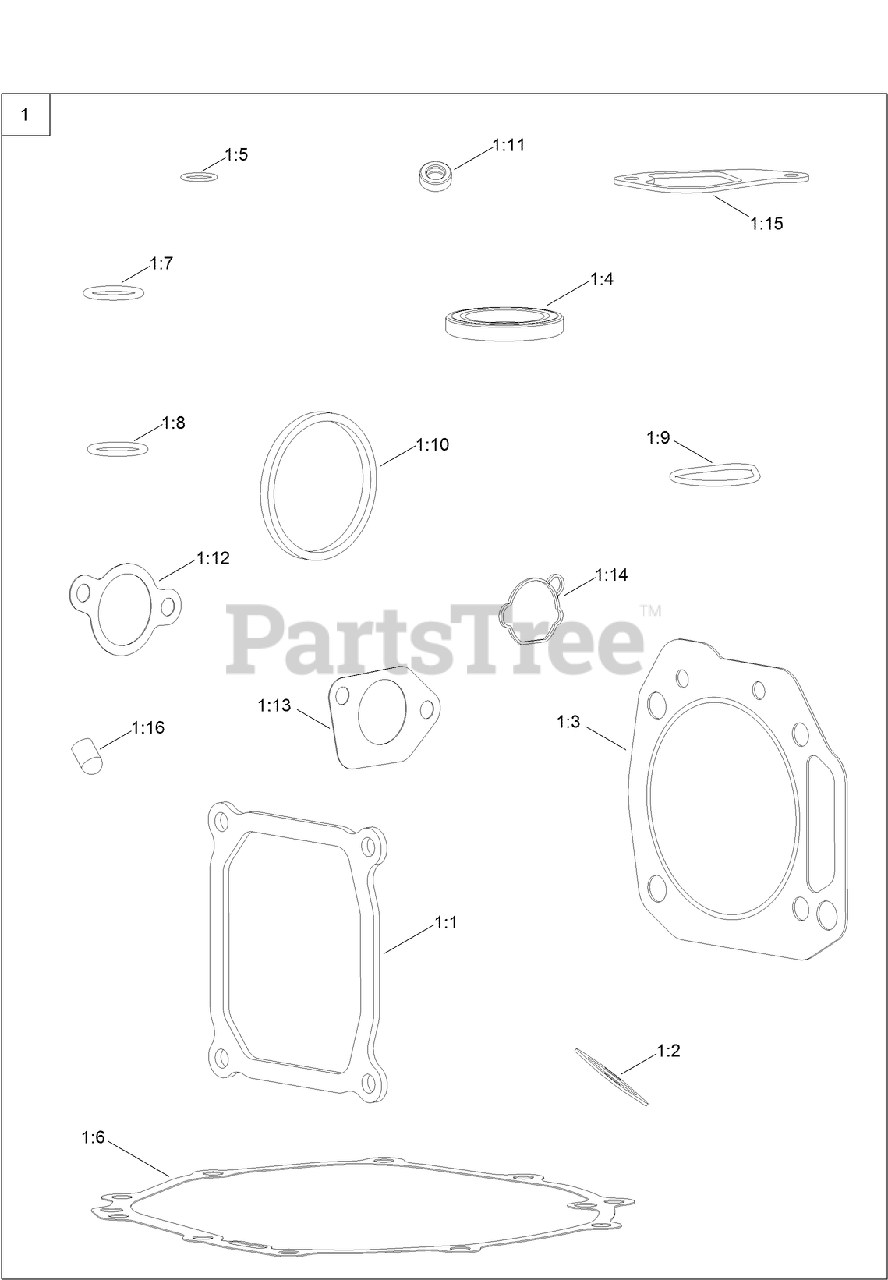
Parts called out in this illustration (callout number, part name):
1	GASKET AND SEAL KIT
1:1	GASKET-COVER, VALVE
1:2	GASKET-EXHAUST
1:3	GASKET-CYCLINDER
1:4	SEAL-OIL
1:5	O-RING
1:6	GASKET-CRANKCASE
1:7	O-RING
1:8	O-RING
1:9	SEAL-PUMP, OIL
1:10	SEAL-ADAPTOR, OIL
1:11	SEAL-OIL
1:12	GASKET-CARBURETOR
1:13	GASKET-CARBURETOR
1:14	GASKET-CARBURETOR
1:15	GASKET-BREATHER
1:16	CAP-SEAL
